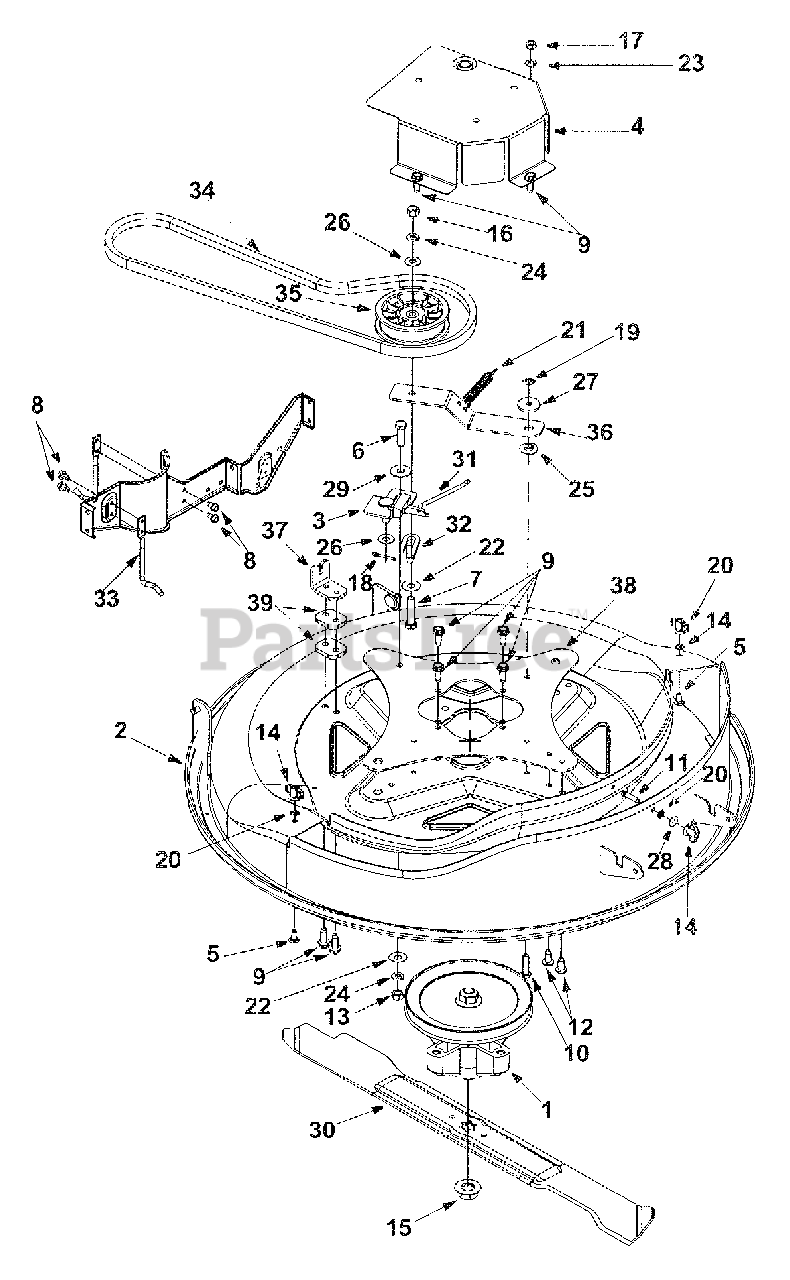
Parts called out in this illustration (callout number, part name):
1	Spindle Assembly
2	Deck Assembly: Yellow
3	Brake Bracket Assembly
5	Carriage Screw 1/4-20 x .62
6	Hex Bolt 3/8-24 x 1.25 Grade 8
7	Hex Screw 3/8-16 x 1.75 Gr. 5
8	Self-Tapp. Screw 1/4-20 x .5
9	Self-Tapp. Screw 5/16-18 x .75
10	Hex Cap Scr. 5/16-24 x 1.25
11	Carriage Screw
12	Torx Screw 5/16-18 x .75
13	Hex Nut 3/8-24
14	Wing Nut With Bell Washer
15	Flange Nut 5/8-18
16	Hex Nut 3/8-16
17	Hex Nut 5/16-24
18	Cotter Pin
19	Speed Nut
21	Extension Spring
22	Flat Washer 3/8 x 1.00 x .030
23	Lock Washer 5/16
24	Lock Washer 3/8
25	Bushing
26	Flat Washer .406 x .875 x .059
27	Flat Washer .330 x 1.25 x .120
28	Flat Washer
29	Spacer
32	Belt Keeper
35	Flat Idler Pulley
